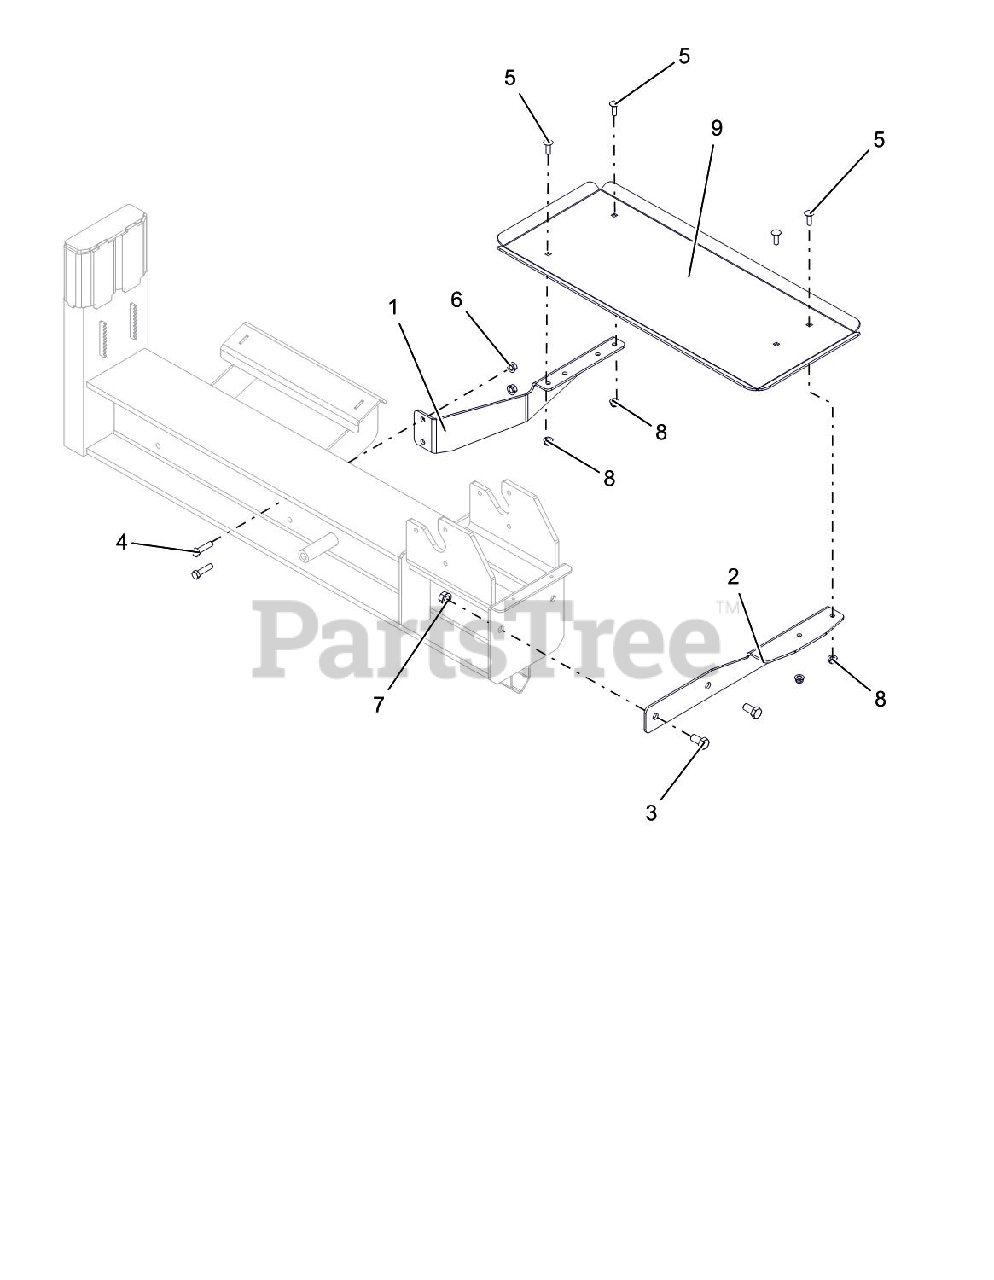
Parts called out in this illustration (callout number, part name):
1	BRKT, REAR TABLE MOUNT
2	BRKT, FRONT TABLE MOUNT
3	@BLT-HEX .50-13X1.00 GR5 YWZC
4	@BLT-HEX .38-16X1.50 GR5 YWZC
5	@BLT-RHDSSQNK .31-18X1.00 G5YZ
6	@NUT-LK-TOP-FLG .38-16 YWZC
7	@NUT-LK-TOP-FLG .50-13 YWZC
8	@NUT-LK-NYL-FLG .31-18 YWZC
9	WORK TABLE W/SAFTY DECAL-27TCE
